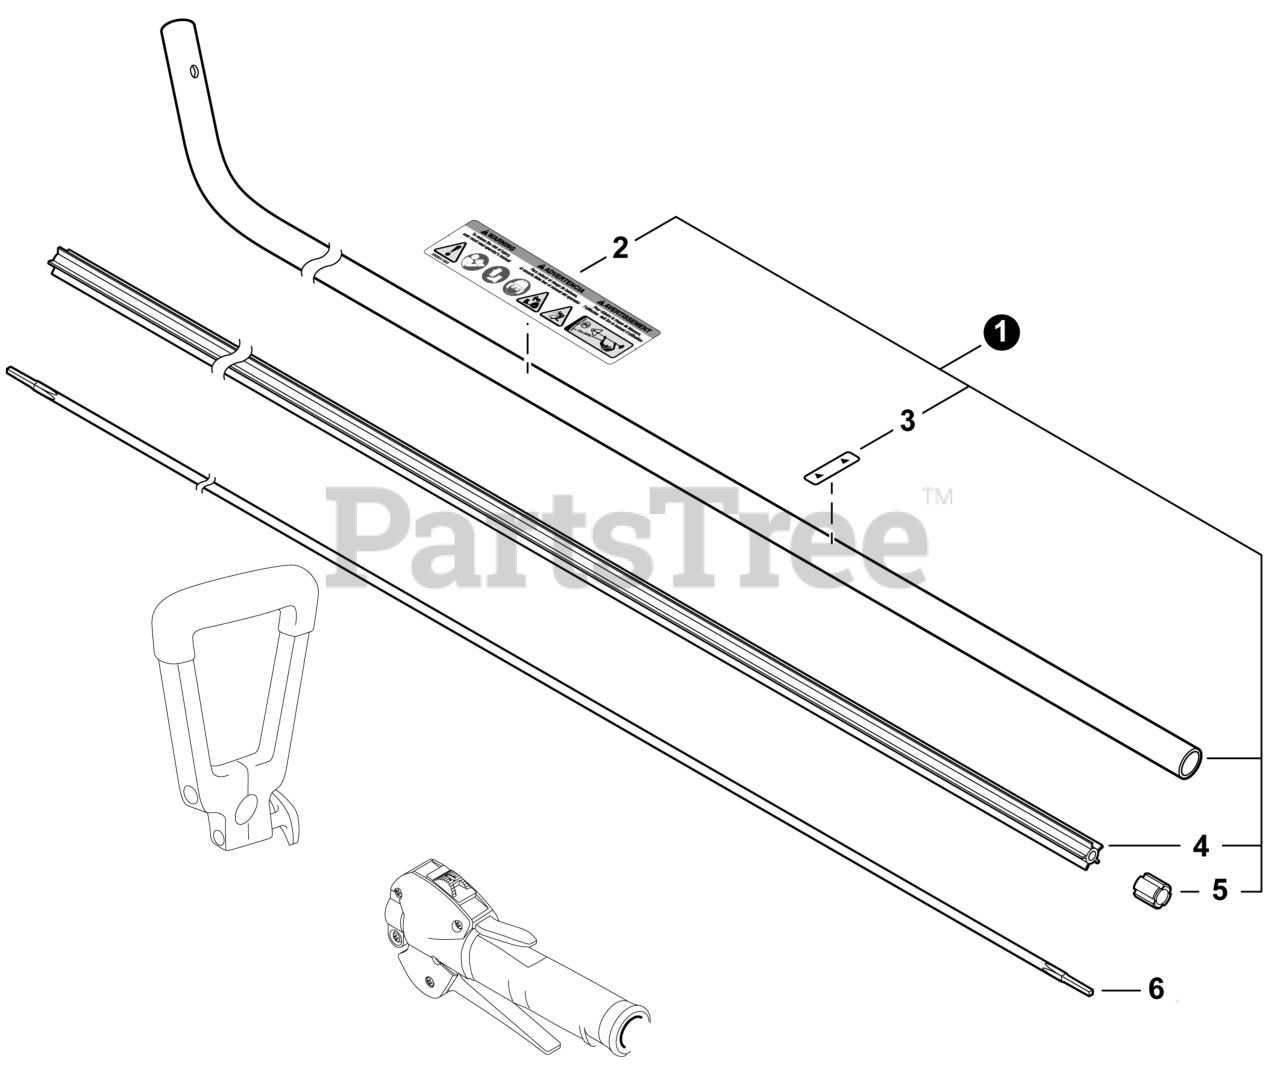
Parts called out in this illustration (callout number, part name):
1	MAIN PIPE ASSY
2	LABEL - CAUTION ISO
3	LABEL - ALIGNMENT
4	LINER, FLEXIBLE
5	STOPPER
6	DRIVESHAFT - FLEXIBLE
